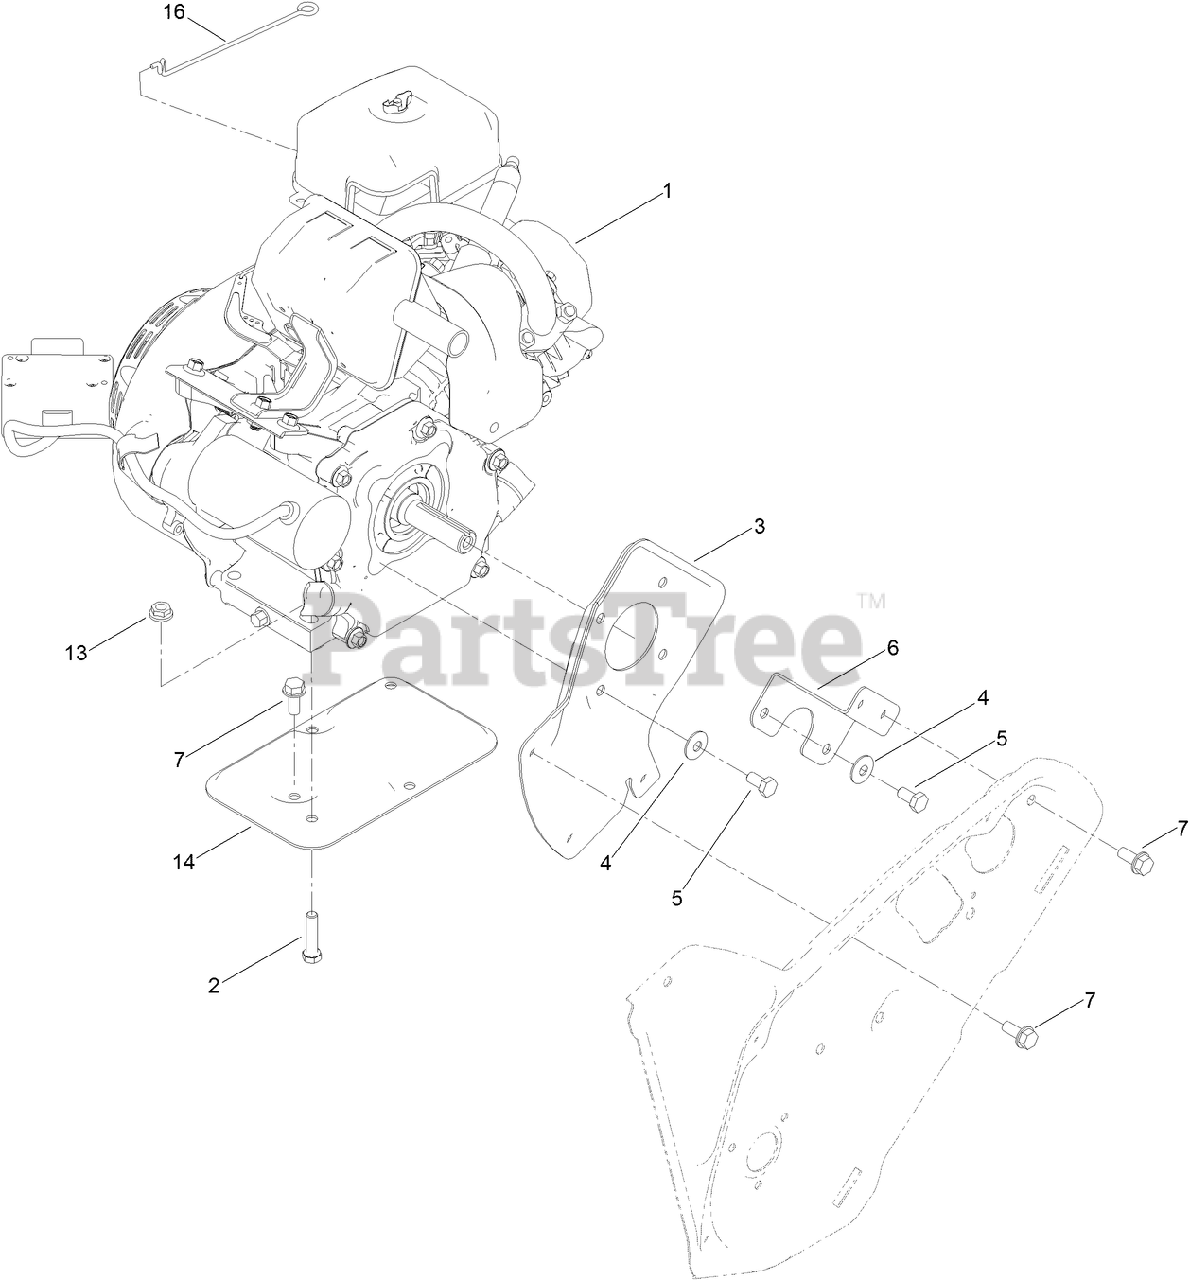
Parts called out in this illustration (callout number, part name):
1	ENGINE-170FS-2
2	SCREW-HH
3	PLATE-ENGINE, PTO
4	WASHER-BELLEVILLE
5	SCREW-HH
6	SUPPORT-ENGINE, SIDE
7	SCREW-THD ROLL, HWH
13	NUT-HF
14	SUPPORT-ENGINE
16	LINK-CHOKE
